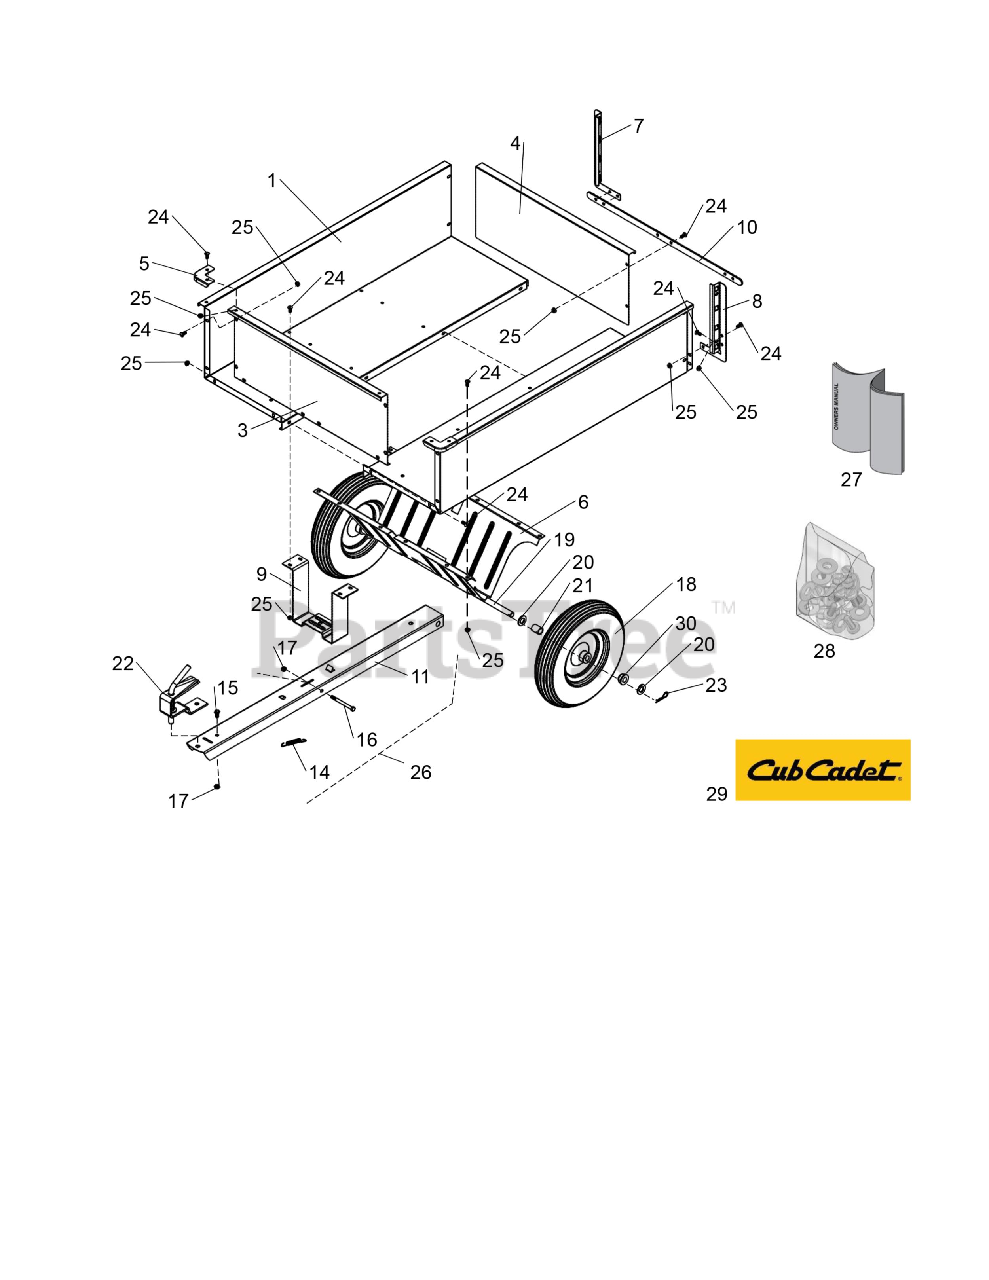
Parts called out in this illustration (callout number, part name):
1	Body Half (Rh)
1	Body Half (Lh)
5	Corner Guard
6	Undercarriage
7	Retainer Gate (Rh)
8	Retainer Gate (Lh)
9	Support Front
10	Rear Bar Support
11	Drawbar
14	Spring Latch
15	Hex Bolt 3/8-16 X 3/4"
16	Hex Bolt 3/8-16 X 4"
17	Hex Nut 3/8-16 C-Lock
18	Wheel Assembly
20	Washer 3/4" Sae
21	Spacer 3/4"X1.250"
22	Spring Loaded Hitch Bracket
23	Cotter Hairpin
24	Truss Hd Screw 5/16-18 X 3/4"
25	Spinner Grip Nut 5/16-18
26	Drawbar Assembly
27	Manual
28	Hardware Bolt Bag
29	Decal
30	Wheel Bushing Kit 3/4"
